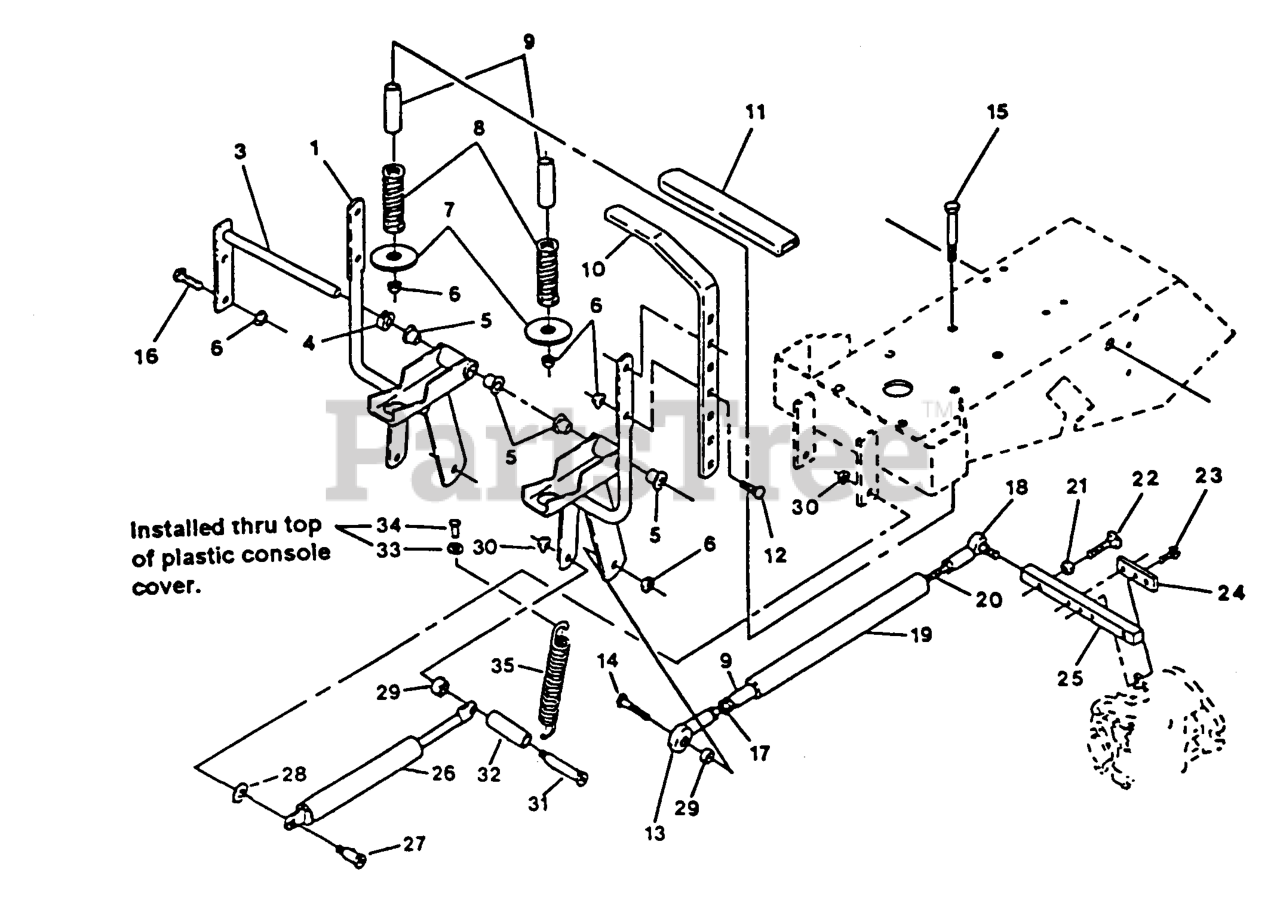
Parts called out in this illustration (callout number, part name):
5	BEARING-CONTROL
7	WSHR,REVERSE INDICATOR
8	SPRING-INDICATOR, REVERSE
9	BUSHING,SPRING GUIDE
11	GRIP,MOTION CONTRL
13	BALLJOINT-RH
18	BALLJOINT
20	ROD,STEERING
24	PLATE,CLAMP
25	ARM,PUMP CONTROL
29	SPACER-PLATED
32	SPACER,MOTION CONTRL PLT
35	SPRING,EXTENSION
